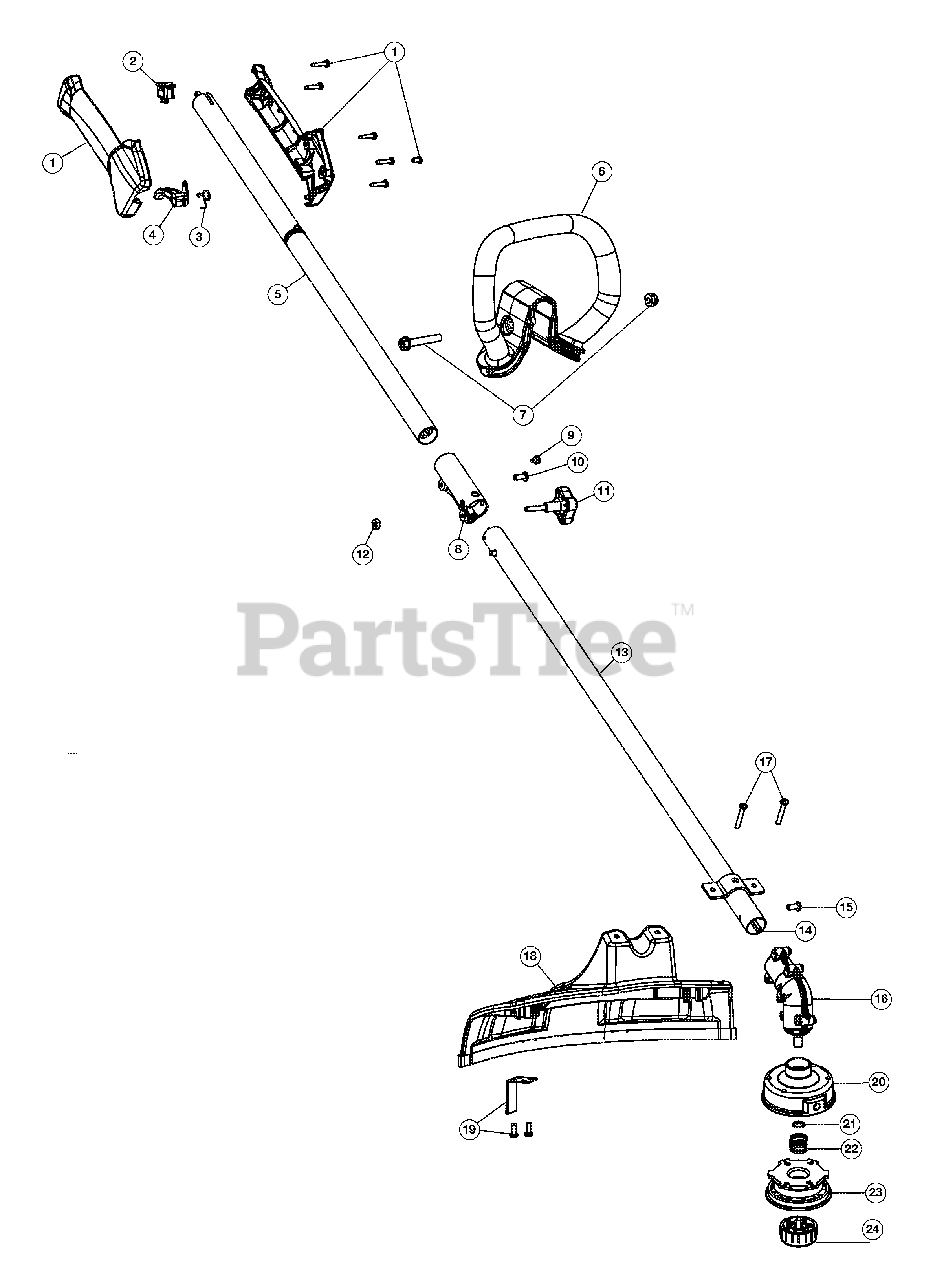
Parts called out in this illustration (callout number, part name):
1	Throttle Housing Assembly (Incl. 2-4)
3	Throttle Trigger
4	Throttle Trigger Spring
5	Upper Drive Shaft Housing Assembly
6	D-Handle (Incl. 7)
7	D-Handle Bolt
8	Split Boom Coupler (Incl. 9-12)
11	Adjustment Knob (Incl. 12)
12	Knob Retaining Nut
13	Lower Drive Shaft Housing Assembly
14	Lower Flexible Drive Shaft
15	Anti-Rotation Screw
16	Gear Box Assembly (Incl. 15 & 20-24)
17	Shield Mounting Screws
18	Shield Assembly (Incl. 17 & 19)
19	Blade Assembly
20	Outer Spool Assembly
23	Inner Reel
24	Bump Knob Assembly
